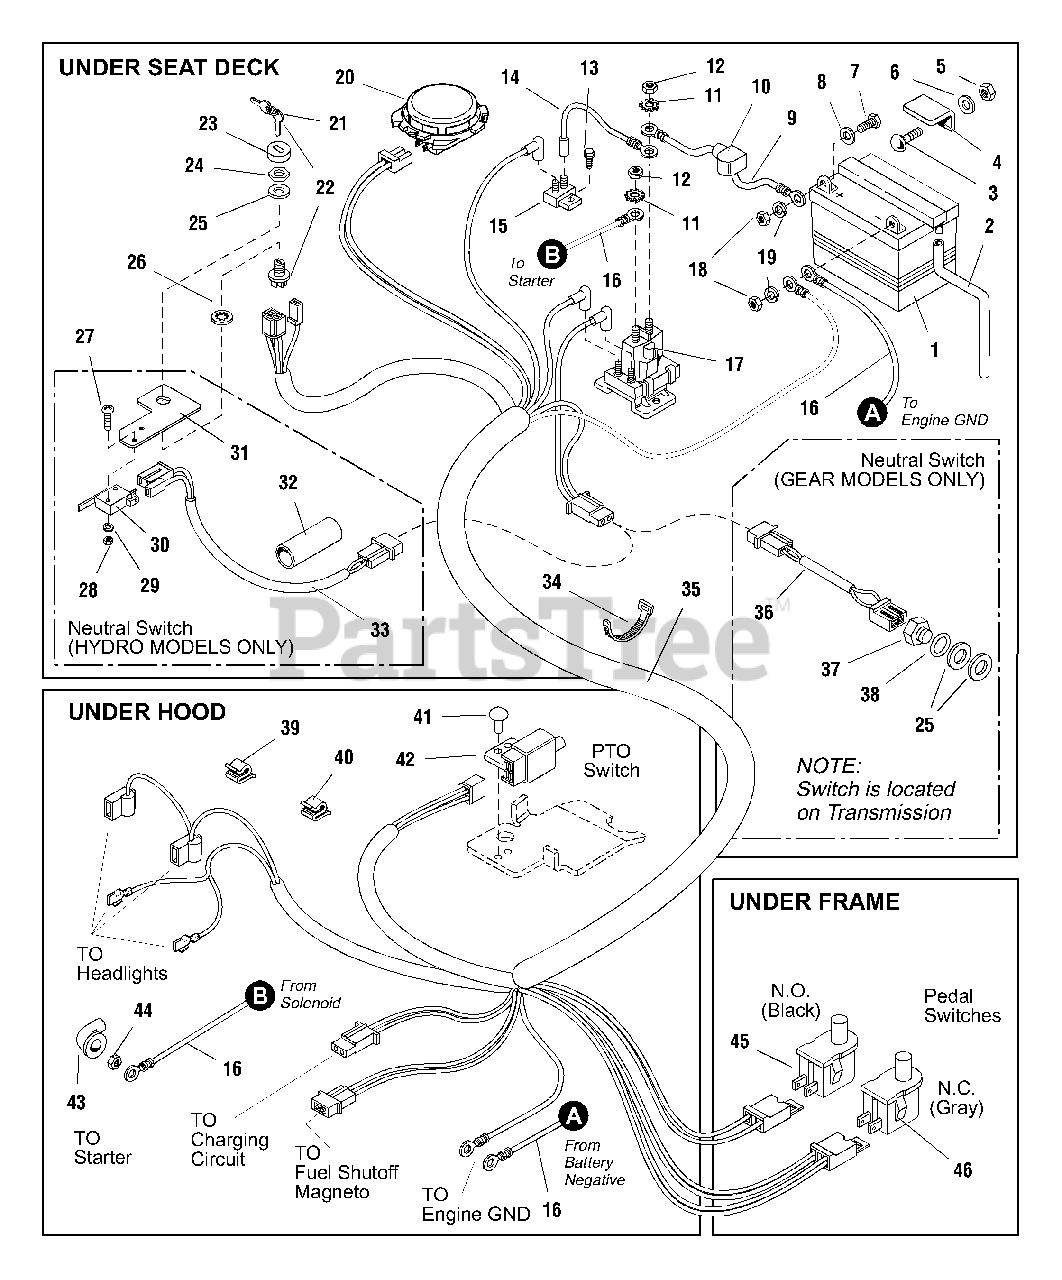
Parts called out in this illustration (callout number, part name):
2	HOSE, Drain
3	CARRIAGE BOLT, 5/16-18 x 3/4
4	CLAMP, Battery
5	NUT, Hex Nylon Lock, 5/16-18
6	WASHER, Plain, 5/16
7	CAPSCREW, Hex Hd., 1/4-20 x 3/4
8	WASHER, Plain, 1/4
9	CABLE, # 6 x 10 Long, with 2 Ring Terminals
10	BOOT, Insulator
11	LOCKWASHER, External Tooth, 5/16
12	NUT, Hex, 5/16-24 NF
13	CAPSCREW, Taptite Hex Washer Hd, 1/4-20 x 5/8
14	WIRE ASSEMBLY
15	CIRCUIT BREAKER
16	CABLE, (Solenoid to Starter & Battery to Ground)
17	SOLENOID
18	NUT, Hex, 1/4-20
19	LOCKWASHER, 1/4
20	SWITCH, Seat
21	IGNITION KEY (Set of 2)
22	SWITCH, Ignition, 6-Pole
23	COVER, Ignition
24	NUT, Hex, Flange, 5/8-32
25	WASHER, 5/8
26	LOCKWASHER, Internal Tooth, 5/8
27	CAPSCREW, Round Hd, Phillips #5 - 40 x 3/4
28	NUT, Hex Machine, #5-40 NC-2B
29	LOCKWASHER, Spring, 1/8
30	SWITCH, Neutral Safety
31	PLATE, Neutral Switch
32	TUBE, Shrink
33	WIRE ASSEMBLY
34	TIE-SELF LOCKING
35	HARNESS, Wiring
36	WIRE ASSEMBLY, Transmission
37	SWITCH, Transmission
38	SEAL, O-Ring
39	CLIP, Tinnerman
40	CLIP, Wire
42	SWITCH, Neutral Start
43	COVER, Terminal
44	NUT, Hex Flange, Whiz Lock, 1/4 - 20
45	SWITCH, Pedal, N.O., Black
46	SWITCH, Pedal, N.C., Gray
